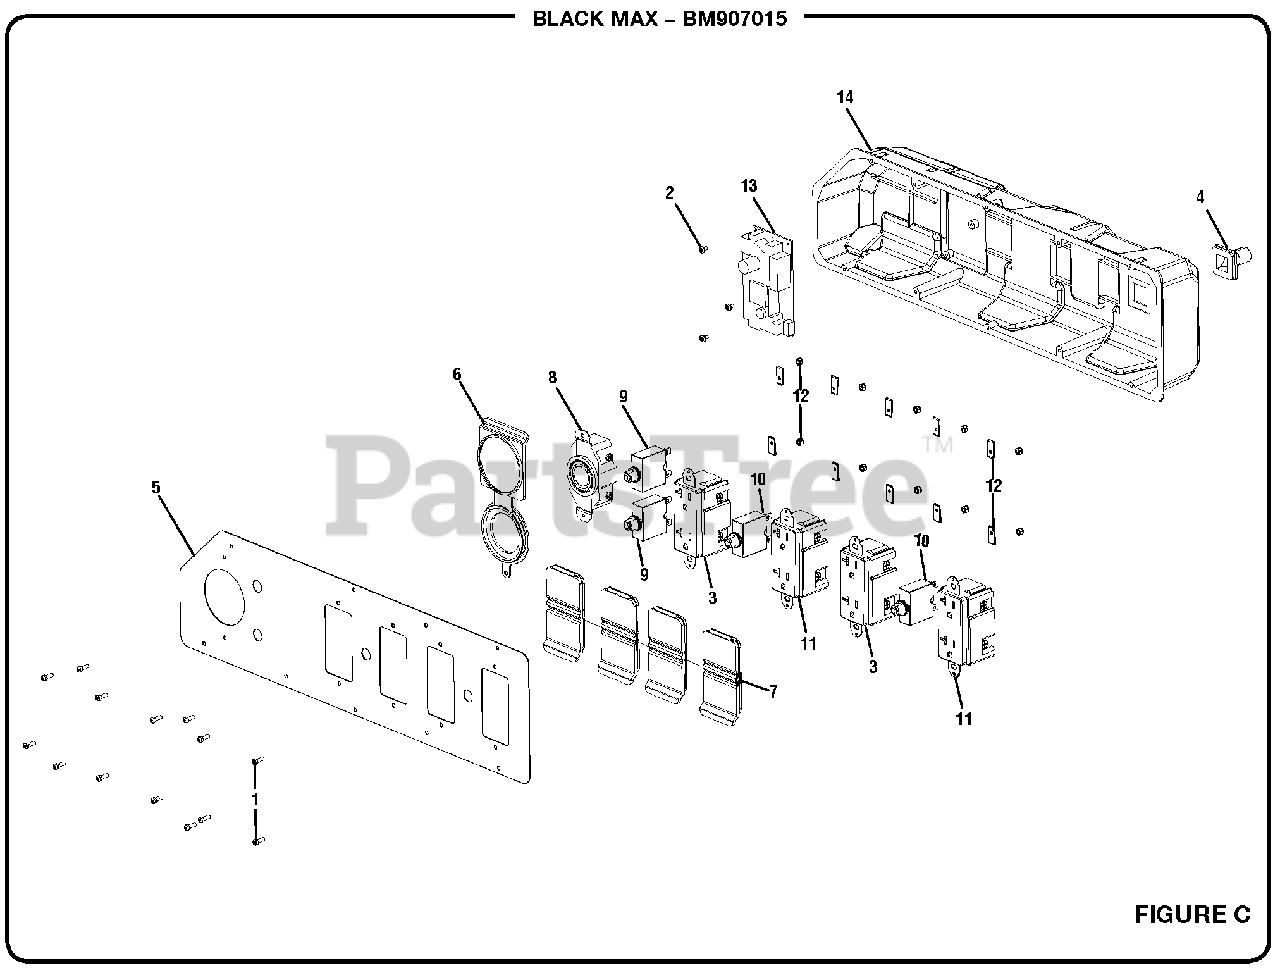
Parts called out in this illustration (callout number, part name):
1	Screw (6-20 x 3/8 in., Phillips Pan Hd.)
2	Screw (M3 x 5 mm, T10 Torx Pan Hd.)
3	120V Duplex Receptacle
4	Wire Protector
5	Control Panel Faceplate
6	Twist Lock Receptacle Cover
7	120V Duplex Receptacle Cover
8	120/240V Receptacle (30A)
9	Circuit Breaker (30A)
10	Circuit Breaker (20A)
11	120V Duplex Receptacle
12	Lock Nut (6-32, Hex Hd.)
13	Circuit Board Assembly
14	Control Box
